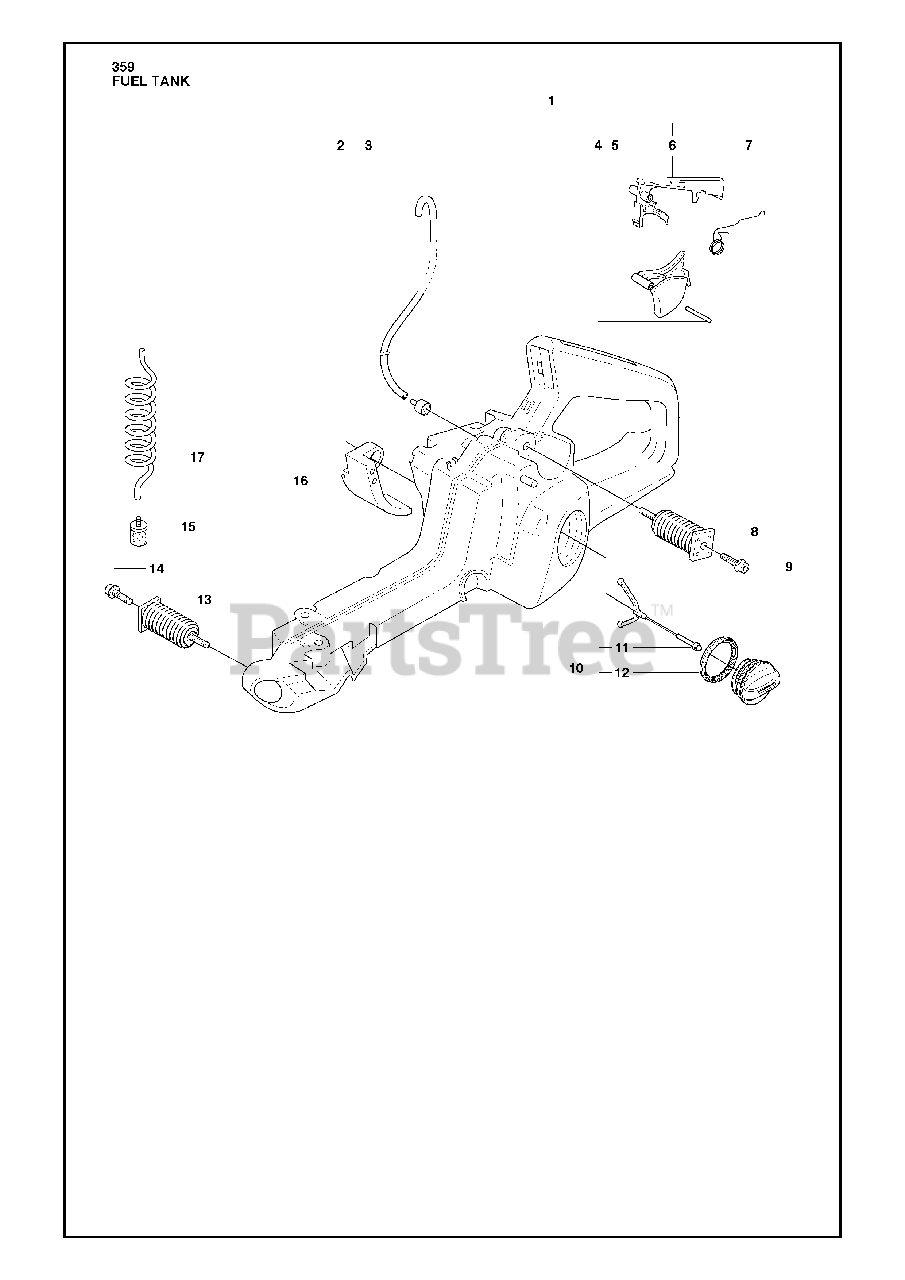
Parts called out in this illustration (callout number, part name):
1	FUEL TANK W/ ACCESSORIES
2	FUEL TANK VENT
3	FUEL HOSE
6	THROTTLE LOCK
8	VIBRATION ABSORBER
10	TANK CAP
12	SEALING
15	FUEL FILTER
17	FUEL HOSE
